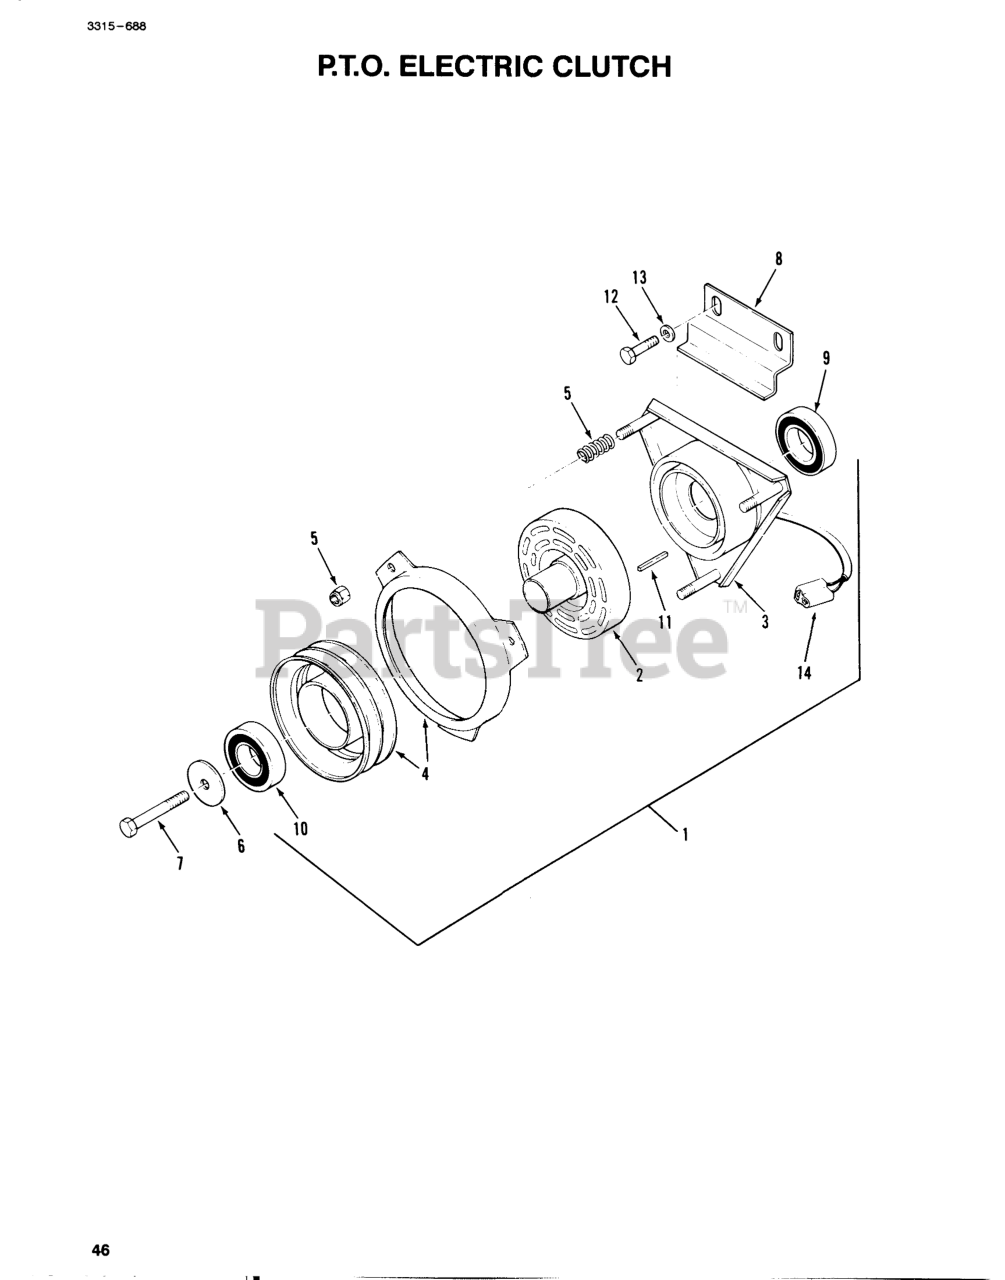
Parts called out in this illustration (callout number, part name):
1	Electric Clutch-Complete (Incl. Items #2, 3, 4, 5, 9, 10, & 14)
2	Rotor
3	Field (Incl. Item #9)
4	Armature & Pulley (Incl. Item #10)
5	Spring & Nuts
6	RETAINER-BEARING
7	SCREW-HH
8	BRACKET-CLUTCH B
9	BEARING-FIELD ASS'Y
10	Bearing
11	KEY-SQUARE
12	SCREW-HH
13	WASHER-FLAT
14	CONNECTOR BODY B
